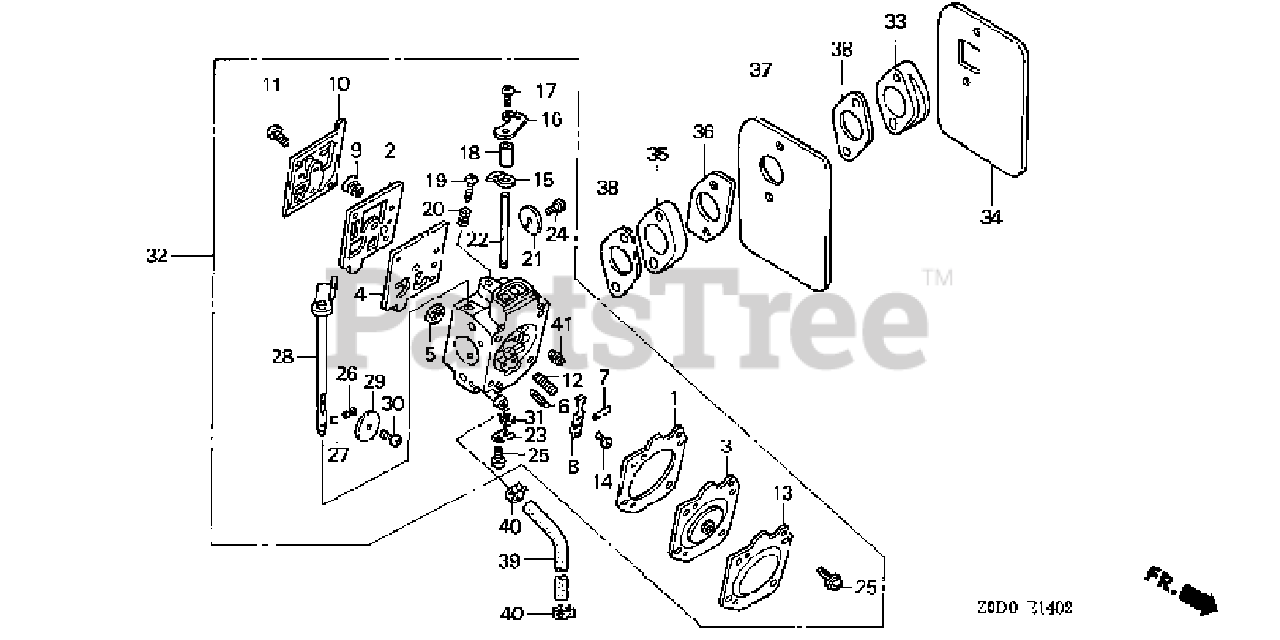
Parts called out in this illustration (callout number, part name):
1	GASKET, METERING DIAPHRAGM
2	GASKET, PUMP
3	DIAPHRAGM ASSY., METERING
4	DIAPHRAGM, PUMP
5	SCREEN, INLET
6	VALVE, IN. NEEDLE
7	PIN, METERING LEVER
8	LEVER, METERING
9	SPRING, PUMP
10	COVER, PUMP
11	SCREW
12	SPRING
13	COVER, METERING DIAPHRAGM
14	SCREW
15	STOPPER, THROTTLE LEVER
16	LEVER, THROTTLE
17	SCREW
18	SPACER, THROTTLE LEVER
19	SCREW, IDLE ADJUSTING
20	SPRING
21	VALVE, THROTTLE
22	SHAFT, THROTTLE
23	CLIP, THROTTLE SHAFT
24	SCREW, VALVE
25	SCREW ASSY.
26	SPRING
27	BALL
28	SHAFT ASSY., CHOKE
29	VALVE, CHOKE
30	SCREW
31	DUST SEAL
32	CARBURETOR ASSY. (HDA 206A)
33	INSULATOR, CARBURETOR
34	GASKET, INSULATOR
35	INSULATOR B, CARBURETOR
36	GASKET B, INSULATOR
37	PLATE, INSULATOR
38	GASKET, CARBURETOR
41	JET (#50)
41	JET (#52)
41	JET (#54)
